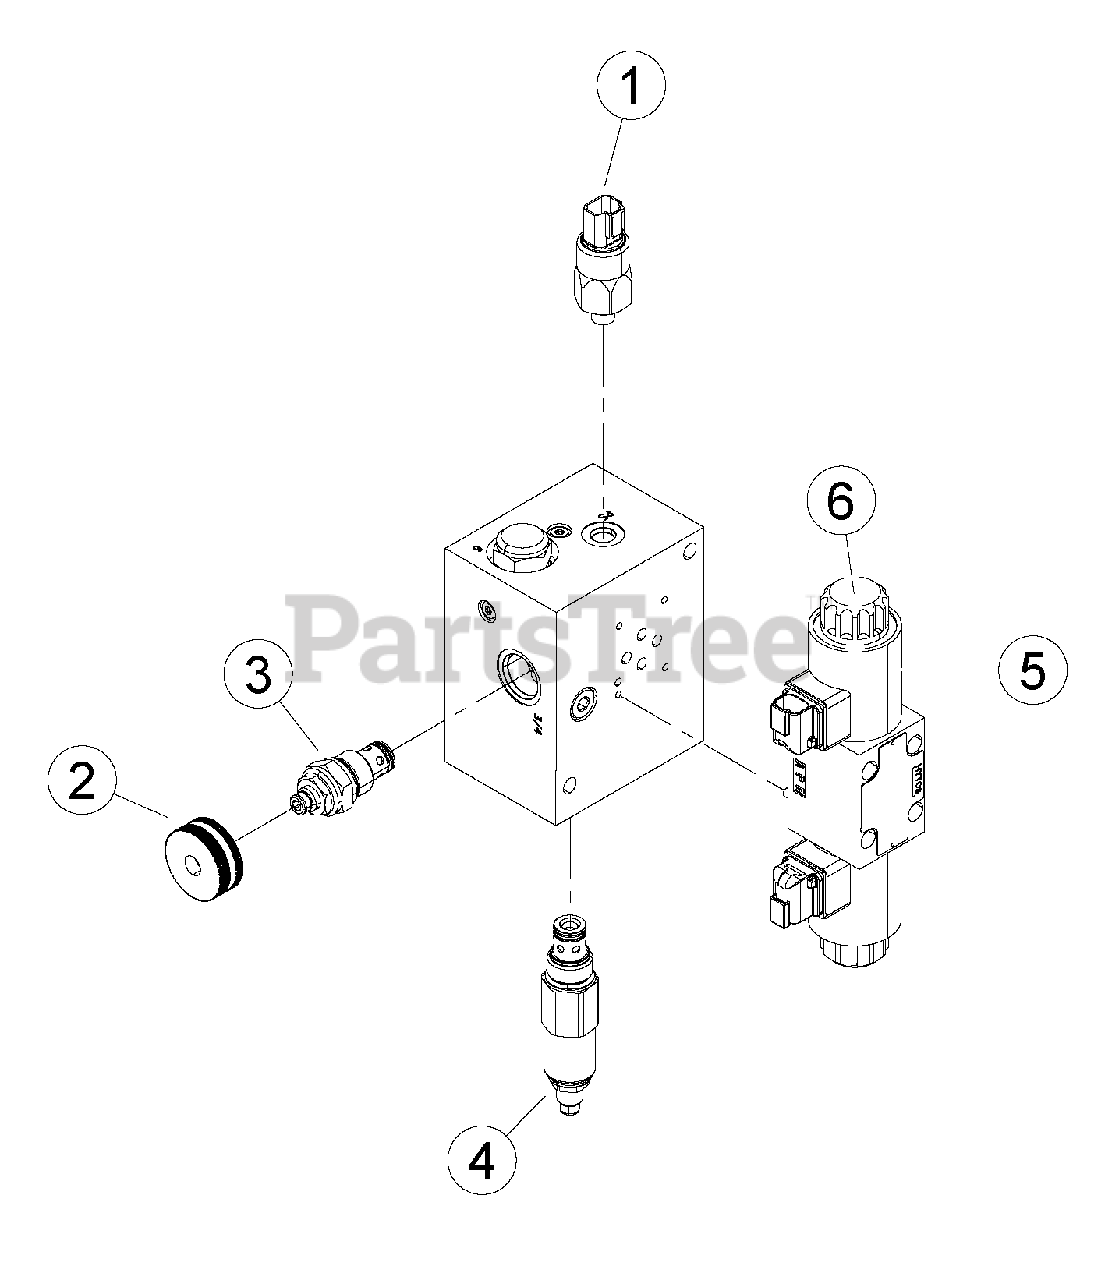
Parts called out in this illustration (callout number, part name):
1	SWITCH, PRESSURE GC
2	KIT, VALVE KNOB
3	VALVE, NEEDLE - 10 MOUNT
4	VALVE, DIFFERENTIAL SENSING
5	COIL, SOLENOID
6	NUT, COIL SOLENOID
